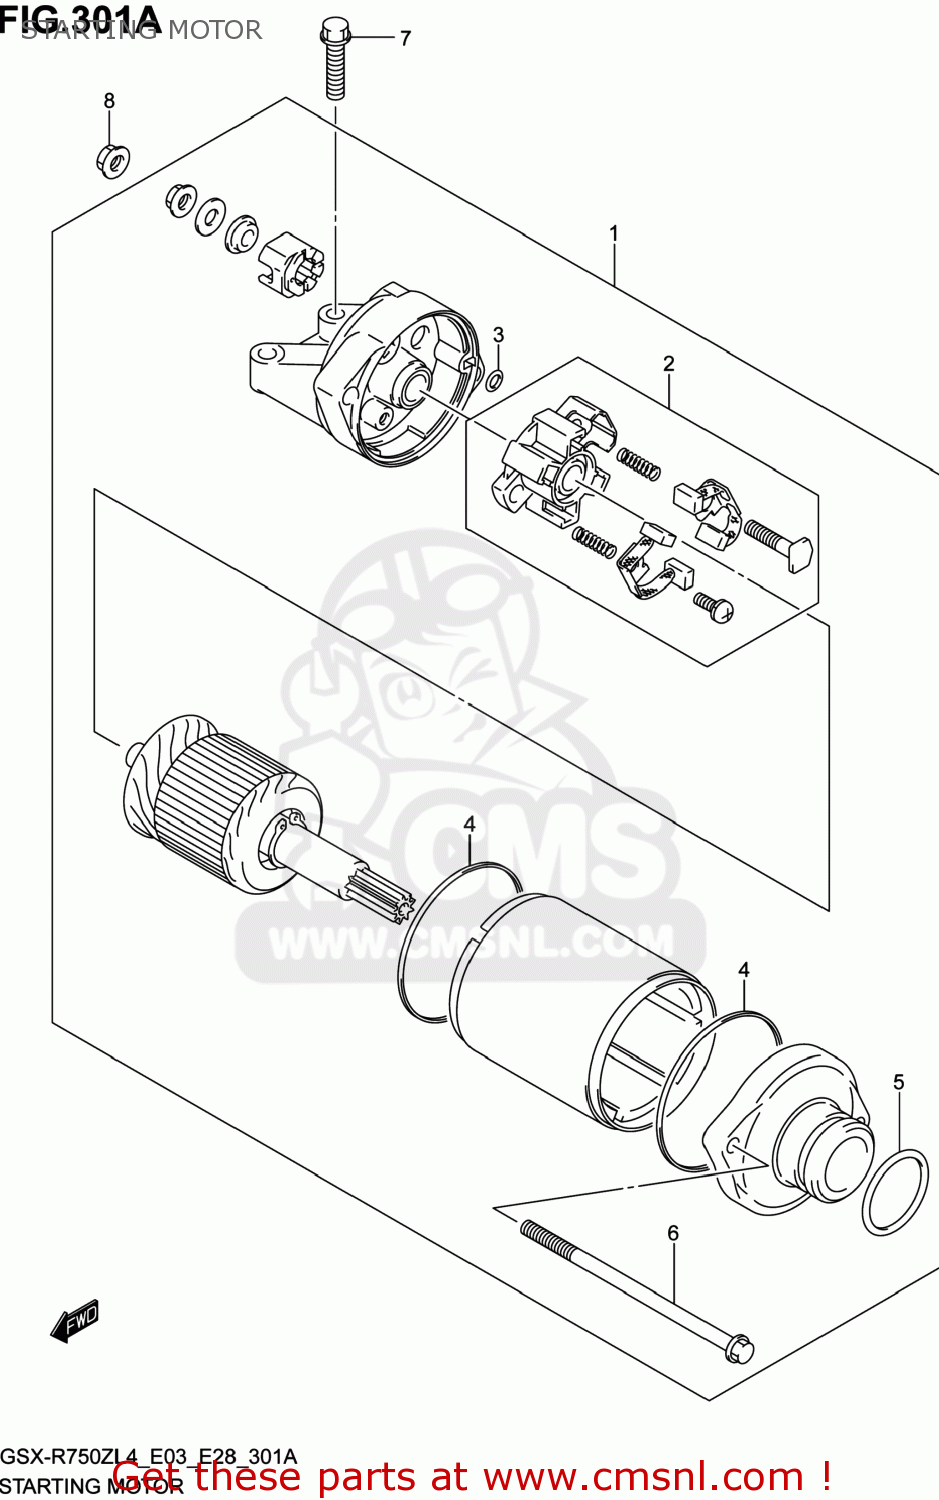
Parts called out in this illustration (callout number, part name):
1	MOTOR ASSY,STARTING
2	BRUSH HOLDER SET
3	O RING
4	SQUARE RING
5	O RING
6	BOLT
7	BOLT(6X25)
8	NUT
